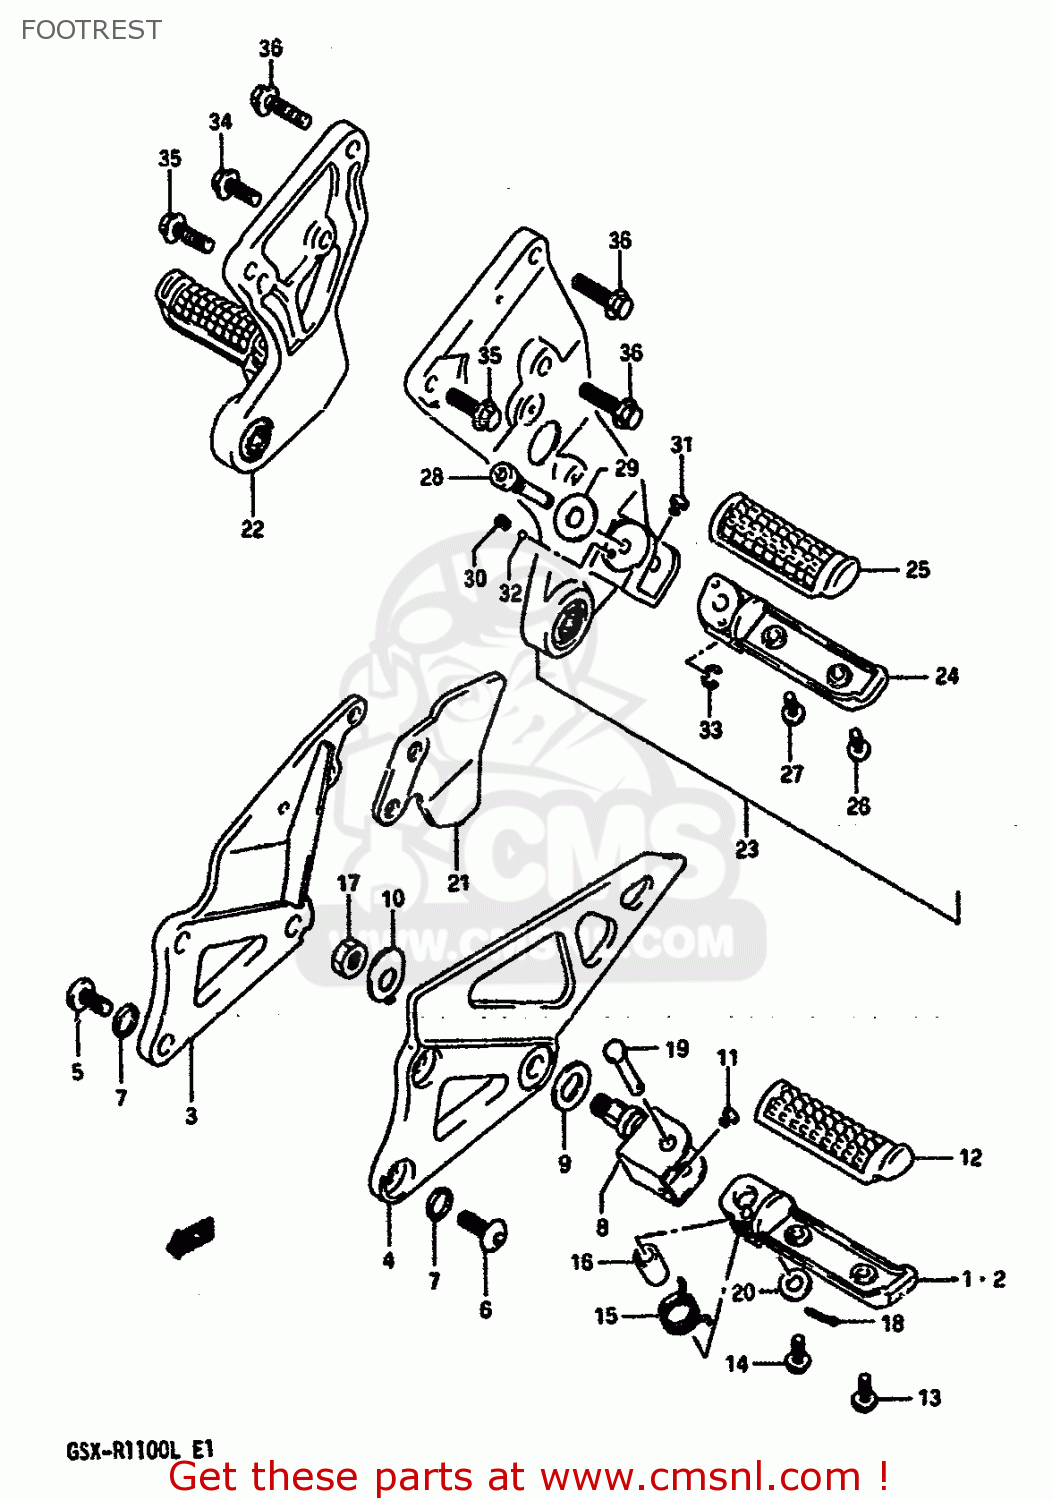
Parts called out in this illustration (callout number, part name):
1	BAR,FOOTREST,R
2	BAR,FOOTREST,L
3	BAR,FRONT FOOTREST
4	BRACKET,FOOTREST,LEFT
5	BOLT,FRONT FOOTREST
6	BOLT,FOOTREST BRACKET
7	WASHER
8	HOLDER,FOOTREST,RIGHT
9	PLATE,FOOTREST INNER
10	WASHER,FR FOOTREST
11	CUSHION,FOOTREST
12	RUBBER,FOOTREST
13	SCREW
14	SCREW
15	SPRING
16	SPACER(8.1X12X22)
17	NUT 12MM
18	PIN 20X15
19	PIN
20	WASHER
21	GUARD,FRONT FOOTREST,RIGHT
22	FOOTREST ASSY,PILLION,R
23	FOOTREST ASSY,PILLION,L
24	BAR,PILLION FOOTREST,R
25	RUBBER,FOOTREST
26	SCREW
27	SCREW
28	BOLT,PILLION FOOTREST
29	WASHER
30	SPRING
31	CUSHION,FOOTREST
32	BALL
33	E RING 6MM
34	BOLT
35	BOLT
36	BOLT
